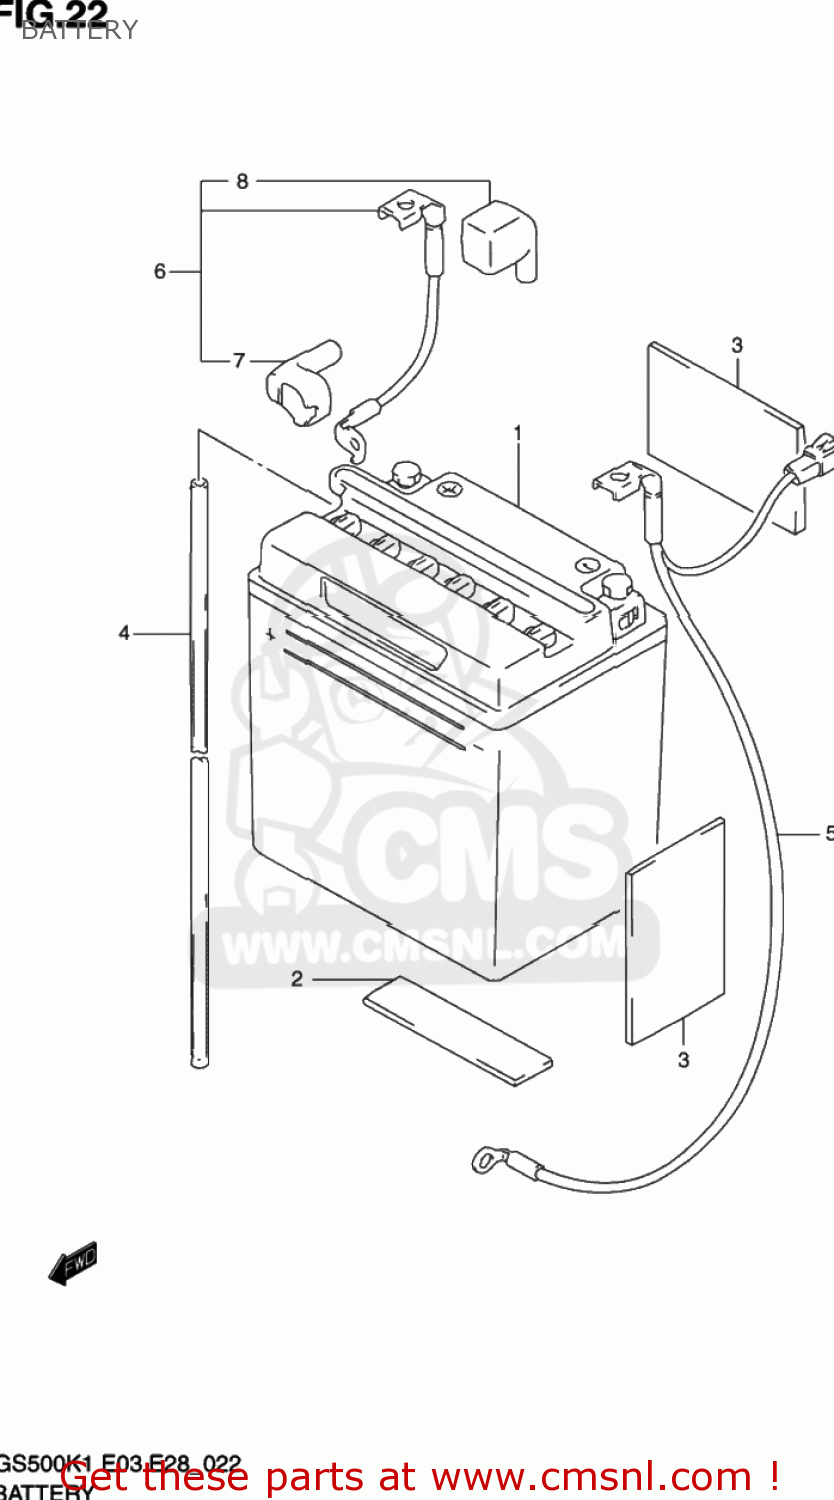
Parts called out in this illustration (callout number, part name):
1	BATTERY ASSY (12V)
2	CUSHION,BATTERY(80X27X3)
3	PROTECTOR(170X95X3.0)
4	HOSE,BATTERY EXHAUST(L:780)
5	WIRE,BATTERY MINUS
6	WIRE,BATTERY PLUS LEAD
7	CAP,STARTER RELAY TERMINAL
8	CAP,BATTERY PLUS TERMINAL
